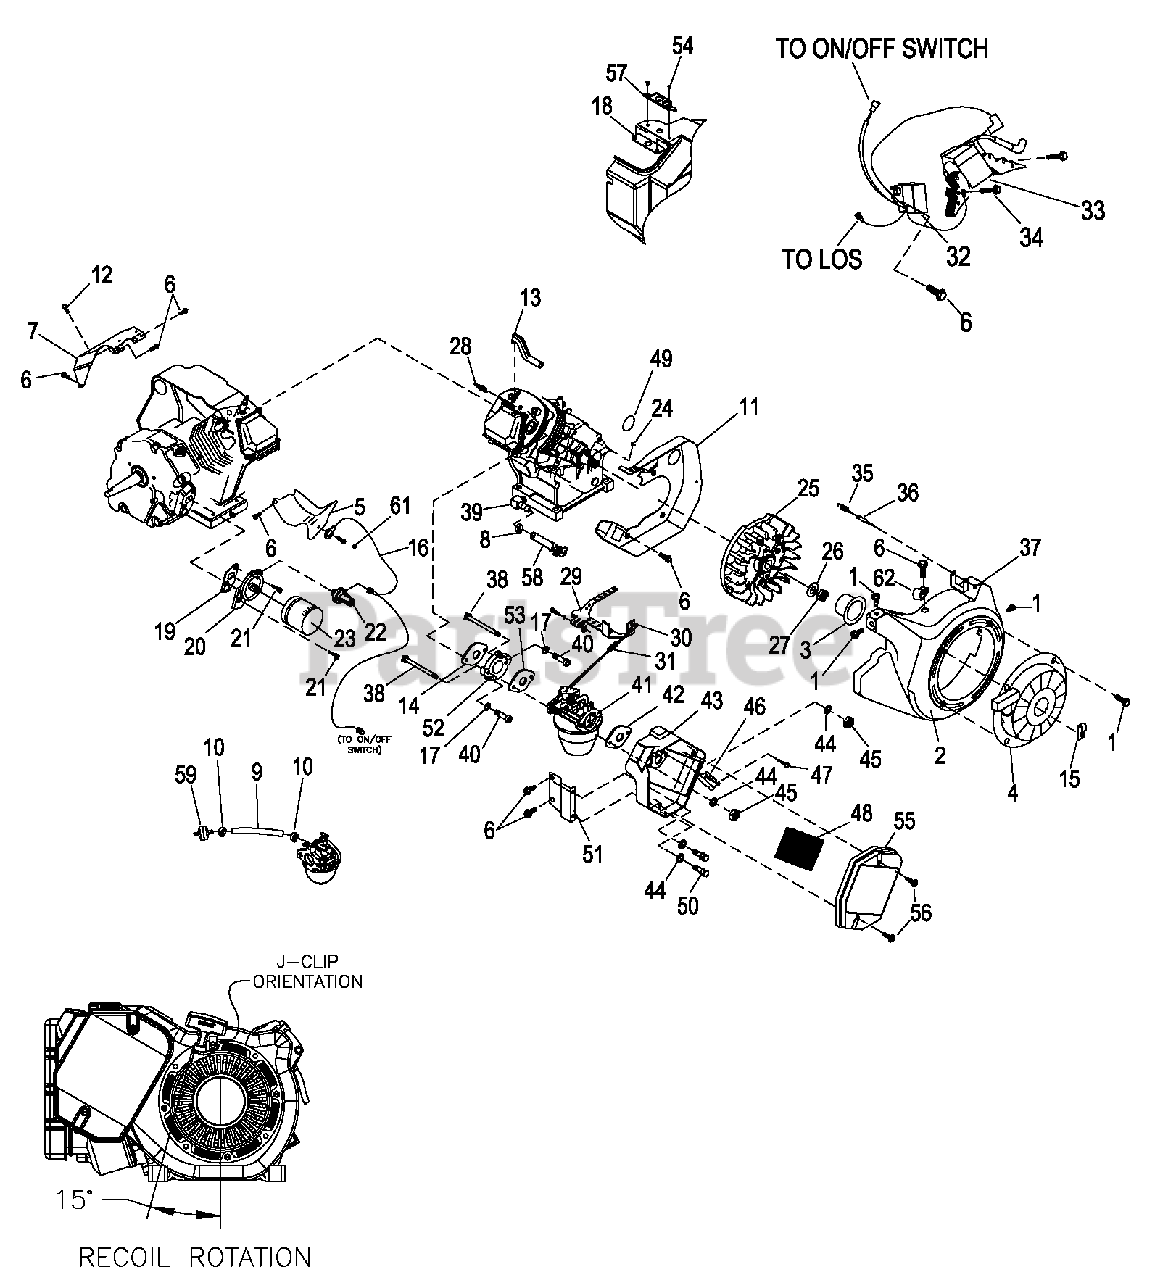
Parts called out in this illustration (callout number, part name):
1	SCREW HHTT M6-1.0 X 8 ZYC
2	ASSEMBLY, BLOWER HOUSING
3	PULLEY STARTER LARGE FRAME
4	RECOIL STARTER LARGE FRAME
5	WRAPPER, BOTTOM 12 HP HS
6	SCREW HHTT M6-1.0 X 10 YELLOW CHROME
7	WRAPPER, TOP REGULAR STEEL
8	CLAMP,HOSE OETIKER STPLSS 18.5
9	FUEL HOSE, 250 MM LONG
10	CLAMP HOSE BAND .41
11	BACKPLATE
12	SCREW, HHTT 5/16-18X1/2" CLEAR
13	HOSE, BREATHER GH410 ENGINES
14	GASKET, INTAKE ADAPTER
15	CLIP-J, VINYL COAT
16	WIRE HARNESS, 410 ENGINE SWITCH WIRING
17	WASHER, LOCK M6-1/4
18	BACK PLATE, SUPPORT
19	GASKET,OIL FILTER ADAPTER
20	ADAPTER, OIL FILTER
21	SCREW, SHC M8-1.25 X 30 G12.9
22	SWITCH, HOBBS OIL PRESSURE 5PSI
23	FILTER, OIL BLACK 75 LONG
24	KEY, WOODRFF 4 X 19D
25	FLYWHEEL, LARGE FRAME 27 DEG
26	WASHER,BELV-20 X 2.2
27	NUT HEX M20-1.5 G8 YLW CHROME- FLYWHEEL
28	SPARKPLUG, CHAMPION RC14YC 0.030"
29	ASSEMBLY,GOVERNOR LEVER 12HP
30	ROD, GOVERNOR CONTROL
31	SPRING, ANTI-LASH
32	OIL PRESSURE SHUTDOWN MODULE
33	ASSEMBLY, IGNITION ADV NO DIODE GH410
34	SCREW, HHTT M6-1.0 X 25 ZINC
35	SPRING GOVERNOR 320/360/410
36	BOLT, GOVERNOR ADJUSTMENT M5
37	NUT, HEX LOCK M5-0.8 NYLON INSERT ZINC
38	BOLT, CARBURETOR MOUNTING
39	BARBED ELBOW 90 DEG 3/8" NPT X 3/8"
40	SCREW, SHC M6-1.0 X 20 G12.9 ZINC PLATED
41	CARBURETOR ASSEMBLY, 410HS
42	GASKET, AIR CLEANER
43	BASE, AIR CLEANER 410 HI FLOW XP PORT
44	WASHER, FLAT M6
45	NUT, HEX LOCK M6-1.0 NYLON INSERT
46	PLATE, SPITBACK
47	SCREW, PLASTITE #8 X .37 LONG
48	ELEMENT, AIR FILTER
49	PLUG PLASTIC 1.875
50	SCREW, HHC M6-1.0 X 16 W/ LOCK WASHER
51	BRACKET, AIR CLEANER
52	ADAPTER, "K"
53	GASKET, CARBURETOR/MANIFOLD
54	RIVET, 1/8"
55	COVER, AIR CLEANER 13GN
56	BOLT, AIR CLEANER COVER
57	BRACKET, CHOKE CABLE
58	ASSY OIL DRAIN HOSE, 6" LONG
59	FUEL FILTER
61	GROMMET
62	C-CLIP STL/VNL .437 X .281
